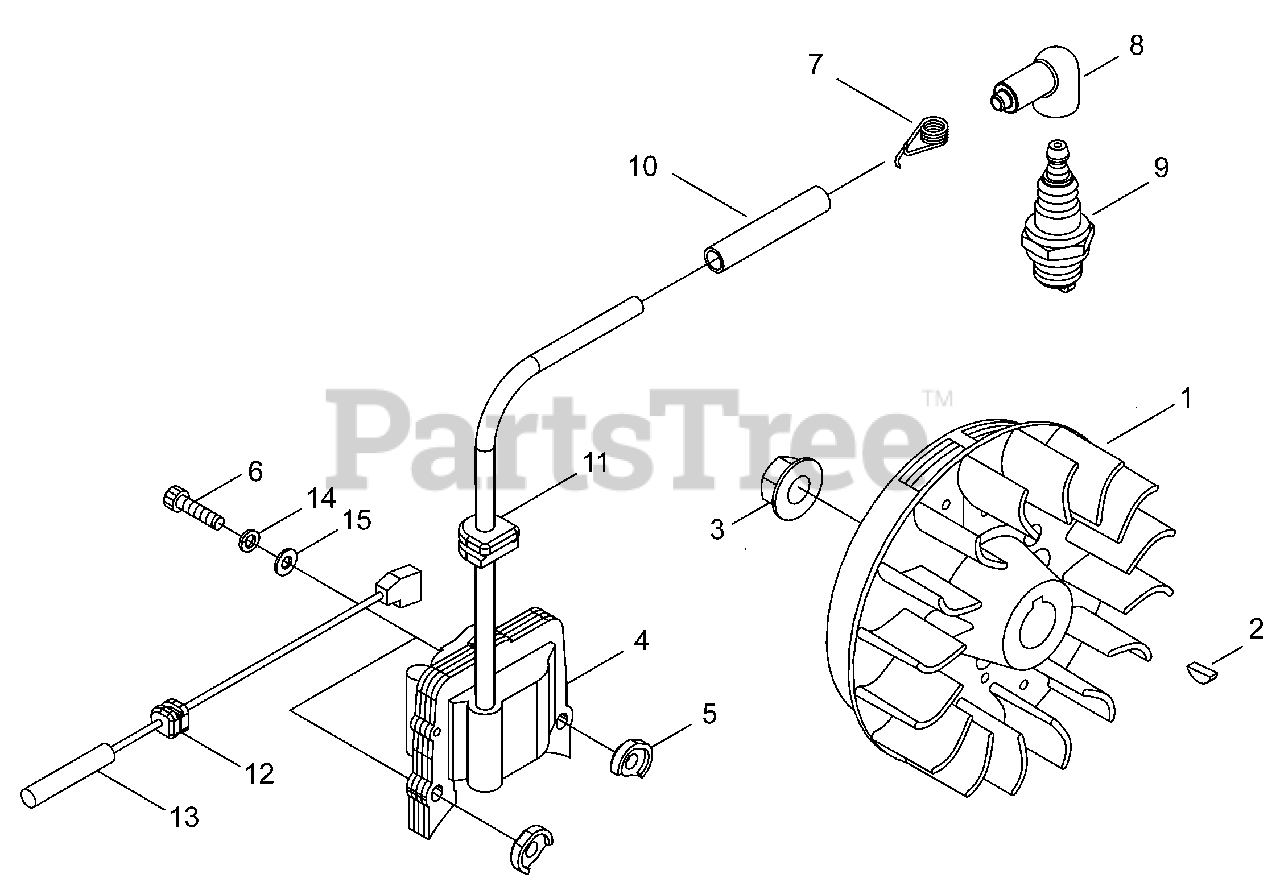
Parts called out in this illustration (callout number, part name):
1	FLYWHEEL
2	KEY, WOODRUFF 3×10
3	NUT, FLANGE M10
4	COIL, IGNITION
5	COLLAR 4
6	BOLT M4×24
7	TERMINAL, SPARK PLUG
8	CAP, SPARK PLUG
9	SPARK PLUG - CJ8
10	TUBE, INSULATOR
11	GROMMET
12	GROMMET, LEAD
13	LEAD - IGNITION
14	WASHER, SPRING 4 MM
15	WASHER 4.3×9.6×0.8
